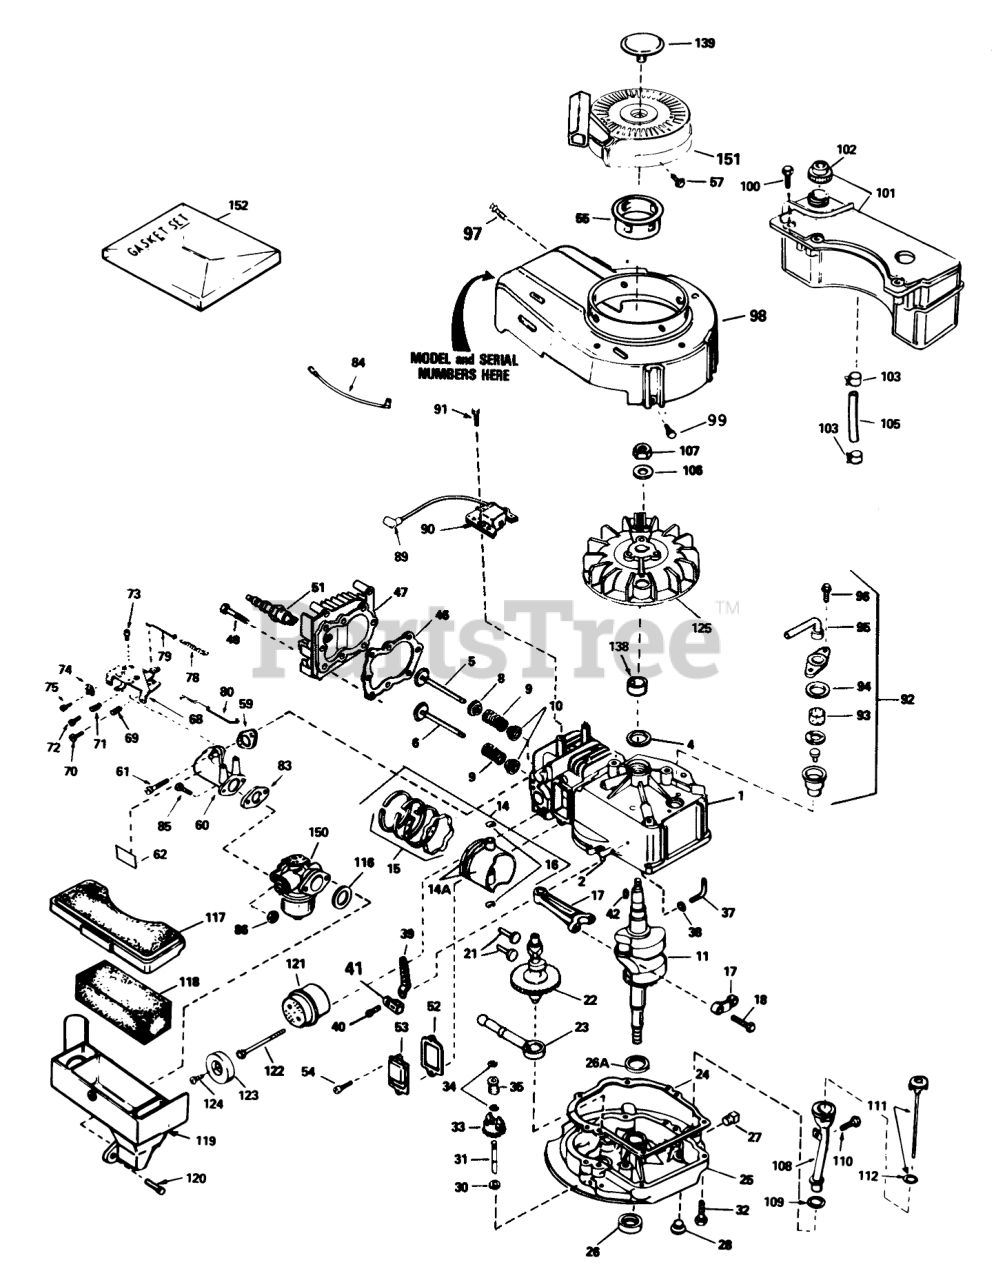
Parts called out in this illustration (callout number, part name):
1	Cylinder Assembly (Incl. Ref. #2 & 4)
2	Pin-Dowel
4	Seal-Oil
5	Valve-Intake (Std.) (Incl. Ref. #10)
5	Valve-Intake (1/32" oversize) (Incl. Ref. #10)
6	Valve-Exhaust (Std.) (Incl. Ref. #10)
6	Valve-Exhaust (1/32" oversize) (Incl. Ref. #10)
8	Seal Assy., Intake
9	Spring-Valve
10	Cap-Valve, Spring
11	Crankshaft
14	Piston-Pin & Ring Assy. (Std.) (Incl. Ref. #14A, 15 & 16)
14	Piston-Pin & Ring Assembly (.010 oversize) (Incl. Ref. #14A, 15 & 16)
14	Piston-Pin & Ring Assembly (.020 oversize) (Incl. Ref. #14A, 15 & 16)
14A	Piston & Pin Assembly (Std.) (Incl. Ref. #16)
14A	Piston & Pin Assembly (.010 oversize) (Incl. Ref. #16)
14A	Piston & Pin Assembly (.020 oversize) (Incl. Ref. #16)
15	Ring Set (Std.)
15	Ring Set (.020" OS)
15	Ring Set (.010" OS)
16	Ring-Retaining, Piston Pin
17	Rod Assembly-Connecting (Incl. Ref. #18)
18	Bolt-Rod, Connecting
21	Lifter-Valve
22	Camshaft(Mech.Comp. Release)
23	Oil Pump ASM
24	Gasket
25	Flange Assembly-Mounting (Incl. Ref. #26, 27, 28 & 31)
26	Seal-Oil
26A	Washer-Thrust
27	Plug-Pipe
28	Plug Oil Drain
30	Washer-Flat
31	Shaft-Governor
32	Screw (1/4-20 x 1-1/4)
33	Gear Assembly-Governor (Incl. Ref. #30)
34	Ring-Retaining
35	Spool-Governor
37	Rod-Governor (Incl. Ref. #38)
38	Washer-Flat
39	Governor Lever
40	Screw
41	Clamp-Lever, Governor
42	Key-Flywheel
46	63573 GIL 42 SNWTHW
47	Head-Cylinder
48	Screw (5/16-18x1-1/2)
51	Plug, Spark (Autolite 458, Champion J-19LM or equiv.)
52	Gasket-Breather
53	Cover-Valve
55	Hub-Starter
57	Screw, Hex Hd.
59	Gasket-Intake
60	Pipe-Intake (Incl. Ref. #59)
61	Screw (1/4-20 x 1)
62	Decal-Primer
68	A Control Assy.-Remote Speed (Incl. Ref. #69 thru 72)
69	61709/GIL1515A/95-5
70	Screw
71	Spring-Compression
72	Screw
73	Screw (10-24 x 9/16)
74	Conduit
75	Screw (10-32 x 3/8)
78	Spring Governor
79	2035A67 ADD.ASSEMBL
80	Link-Throttle
83	Gasket
84	Wire-Ground
85	Screw (1/4-28 x 7/8)
86	Nut and Lock Washer (1/4-28)
89	Cover-Spark Plug
90	Solid State
91	Screw
92	Breather Assembly (Incl. Ref. #93 thru 96)
93	Element-Breather
94	Gasket-Breather
95	Tube, Breaker
96	Screw (10-24 x 9/16)
97	Screw (10-24 x 9/16)
98	Housing-Blower
99	Screw (1/4-20 x 1/2)
100	Screw (10-32 x 35/64)
101	Tank Assembly-Fuel (Incl. Ref. #102)
102	Cap-Fuel
103	Clamp-Line, Fuel
105	Line-Fuel
106	Washer-Belleville
107	Nut-Flywheel
108	Tube-Oil Fill
110	Screw (10-32 x 1/2)
111	Dipstick-Oil (Incl. Ref. #112)
116	Gasket-Cleaner, Air
117	Cover Air Cleaner
118	Filter-Air Cleaner
119	Body Air cleaner
121	Muffler (Incl. Ref. #122)
123	Cover-Muffler
124	Screw (8-32 x 3/8)
125	Flywheel
139	Plug Starter
150	Carburetor (Inc. Ref. #83)
151	Starter-Rewind
152	Gasket Set (Incl. Items Marked )
